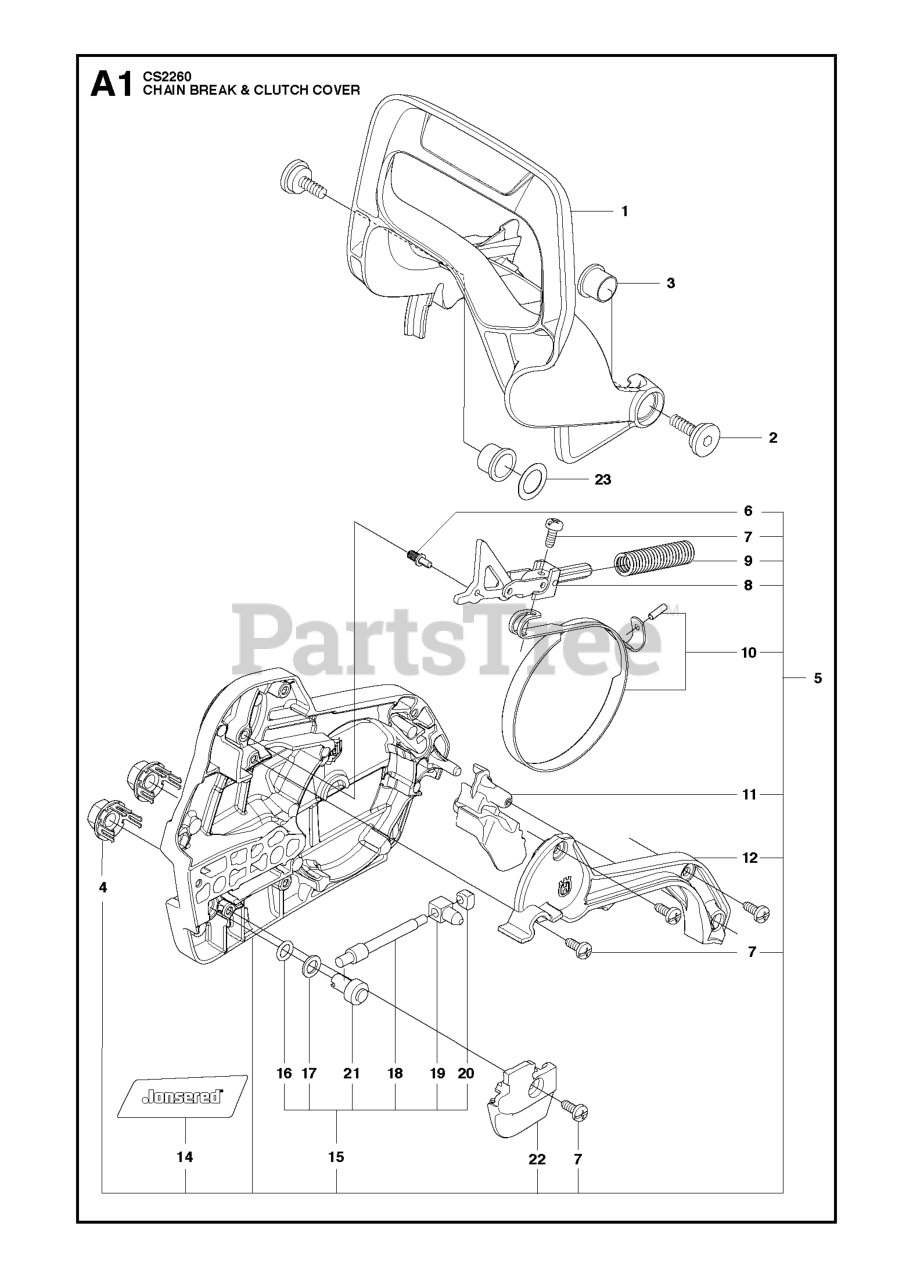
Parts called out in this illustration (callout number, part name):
1	HAND GUARD
4	NUT RETAINER ASSY
5	CLUTCH COVER ASSY
6	PIN
7	SCREW
8	KNEE JOINT ASSY
9	SPRING
10	BRAKE BAND ASSY
11	GUARD
12	COVER BRAKE COVER JONSERED BLA
14	DECAL JONSERED 60CC CLUTCH COV
15	CHAIN TENSIONER KIT
16	O-RING
17	WASHER
18	SCREW
19	PAWL
20	SLEEVE
21	WORM WHEEL
22	CHAIN GUIDE JONSERED BLACK
23	WASHER STEEL
